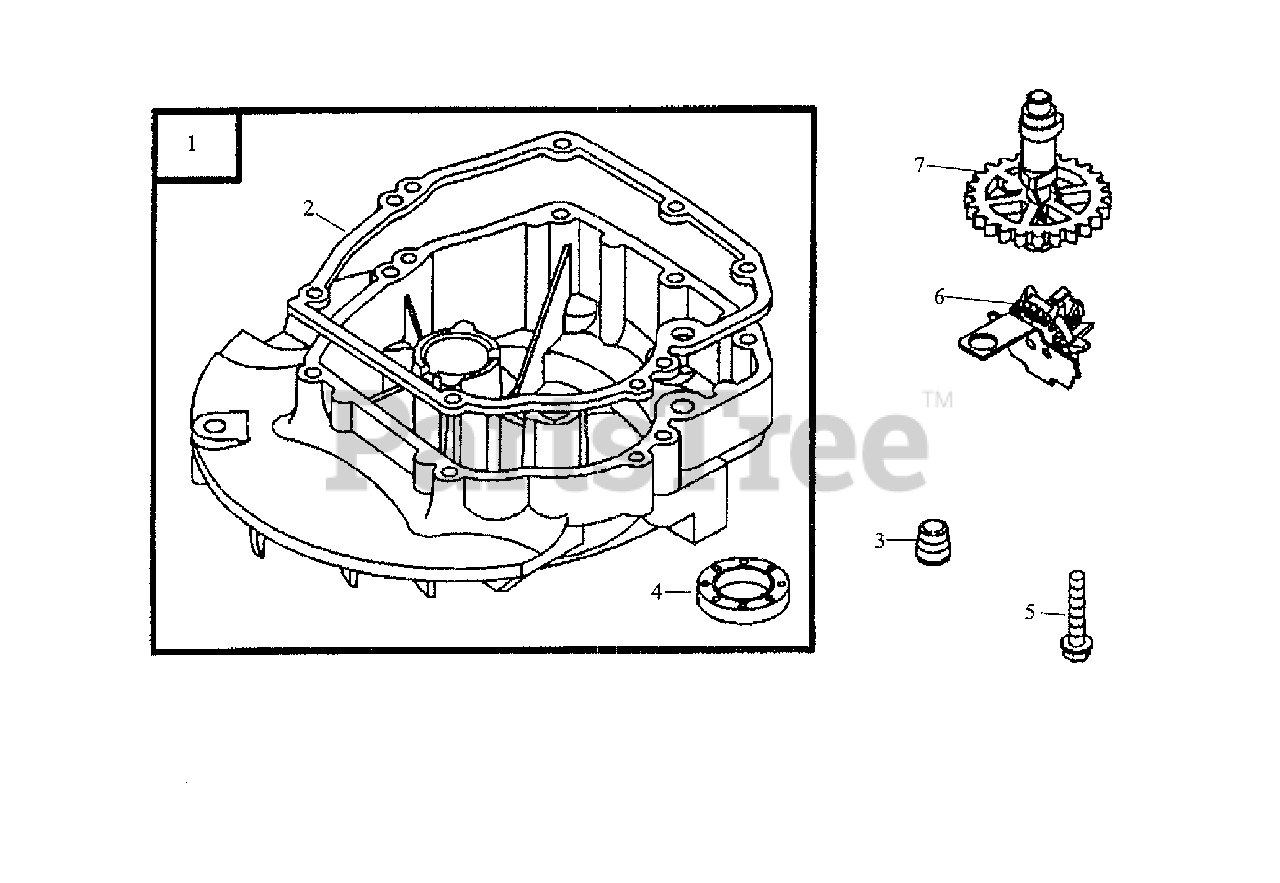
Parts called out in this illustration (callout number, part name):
1	Sump, Engine
2	Gasket, Crankcase
3	Plug, Oil Drain
4	Seal, Oil (PTO Side)
5	Screw, Sump
6	Slinger, Governor/Oil
